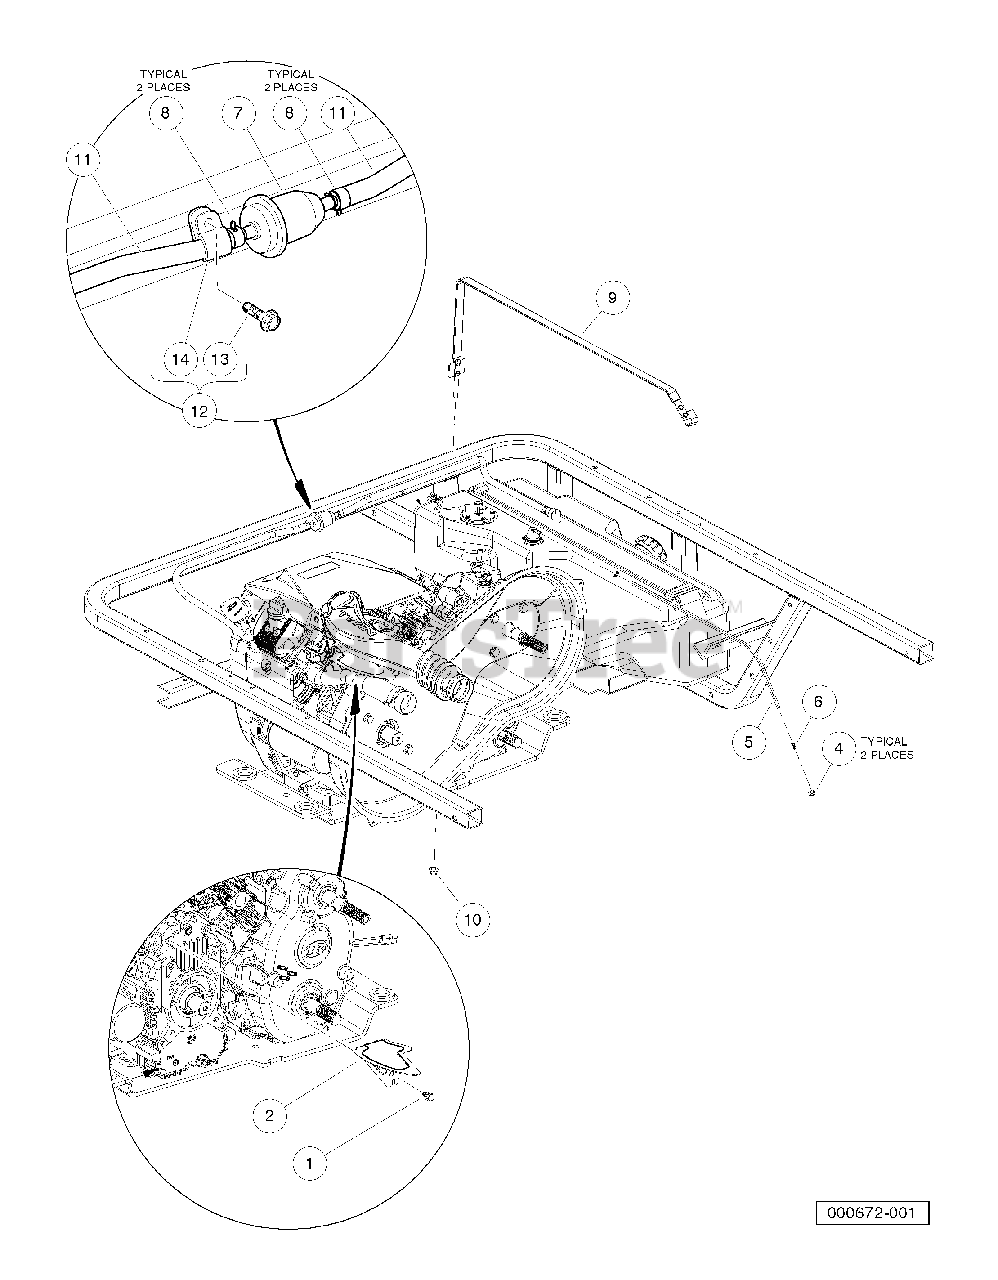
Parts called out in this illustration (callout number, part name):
1	Bolt Flanged Head, M8 X1.25x 16 with Loctite
2	Heat Shield, Header, Gas
4	Clamp, 0.301 ID Hose
5	Hose, Fuel, Vent, 22" Long
7	Filter, Fuel, 30 Micron
8	Clamp, Hose, Ctb 13mm
9	Strap, Tank, Fuel
10	Lock Nut, Flg M8 X 1.25 Nylon
12	Kit, Fuel Line Clamp, 4x4 Khi
13	Screw, M8X1.25X30, Hex
14	P-clamp, Insulated 0.625 In
15	Instr, Kit Fuel Line 4x4 Khi
